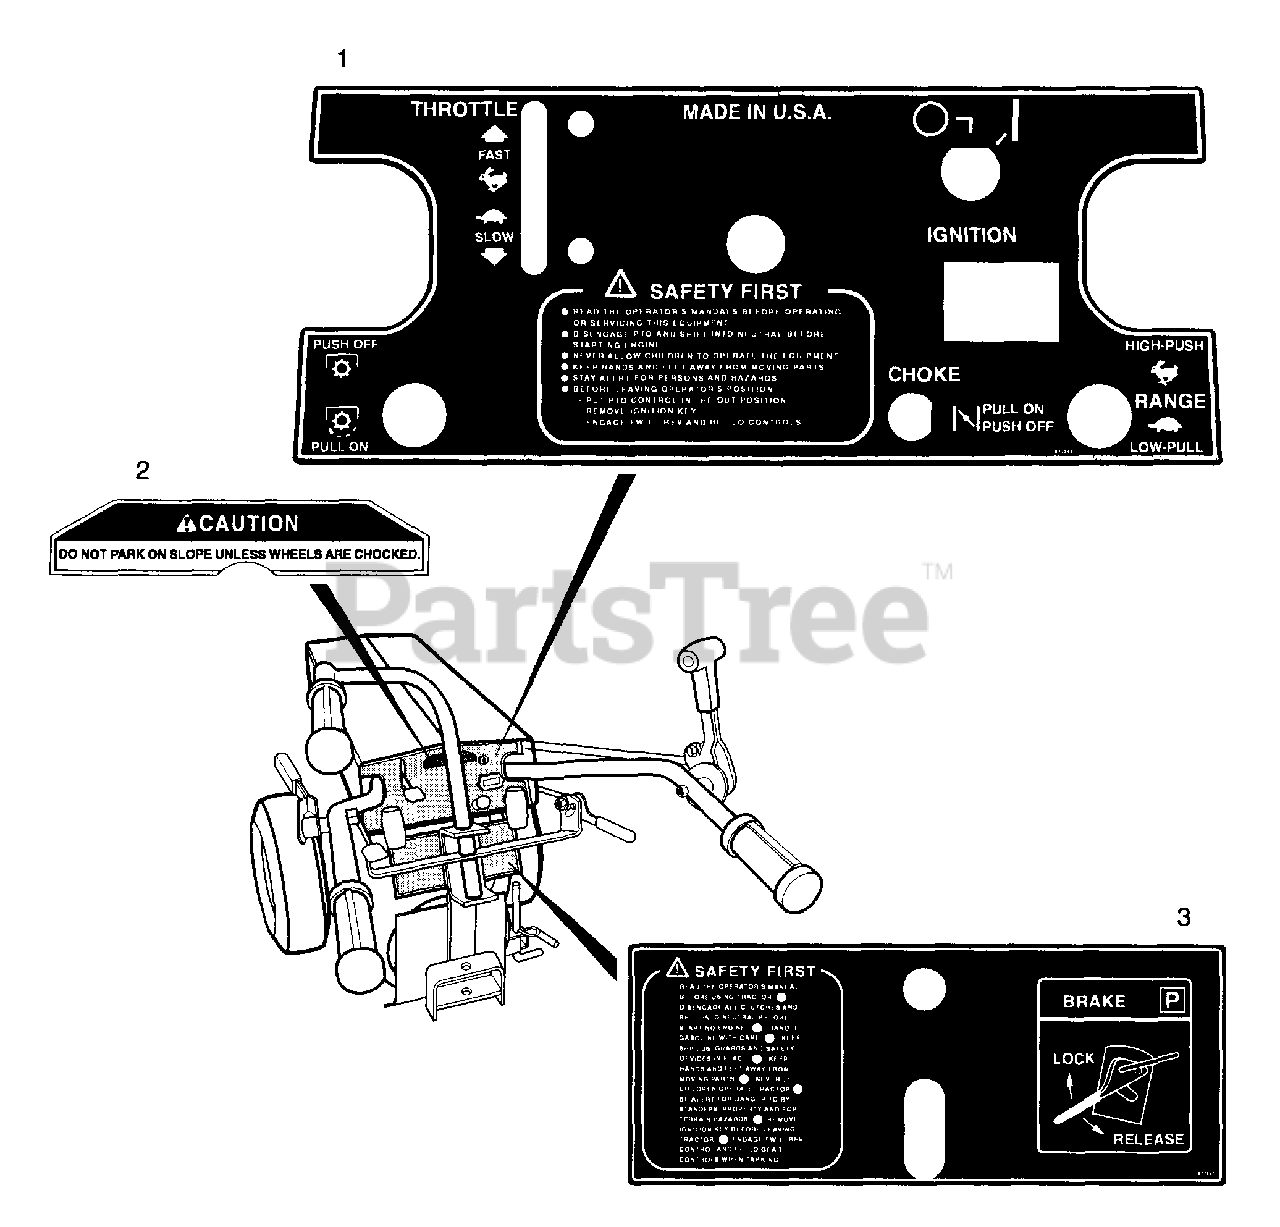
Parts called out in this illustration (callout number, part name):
1	Decal, Instr Panel, 2 Wheel Tractor
2	Decal, CAUTION
3	Decal, 2 Wheel Instructions
